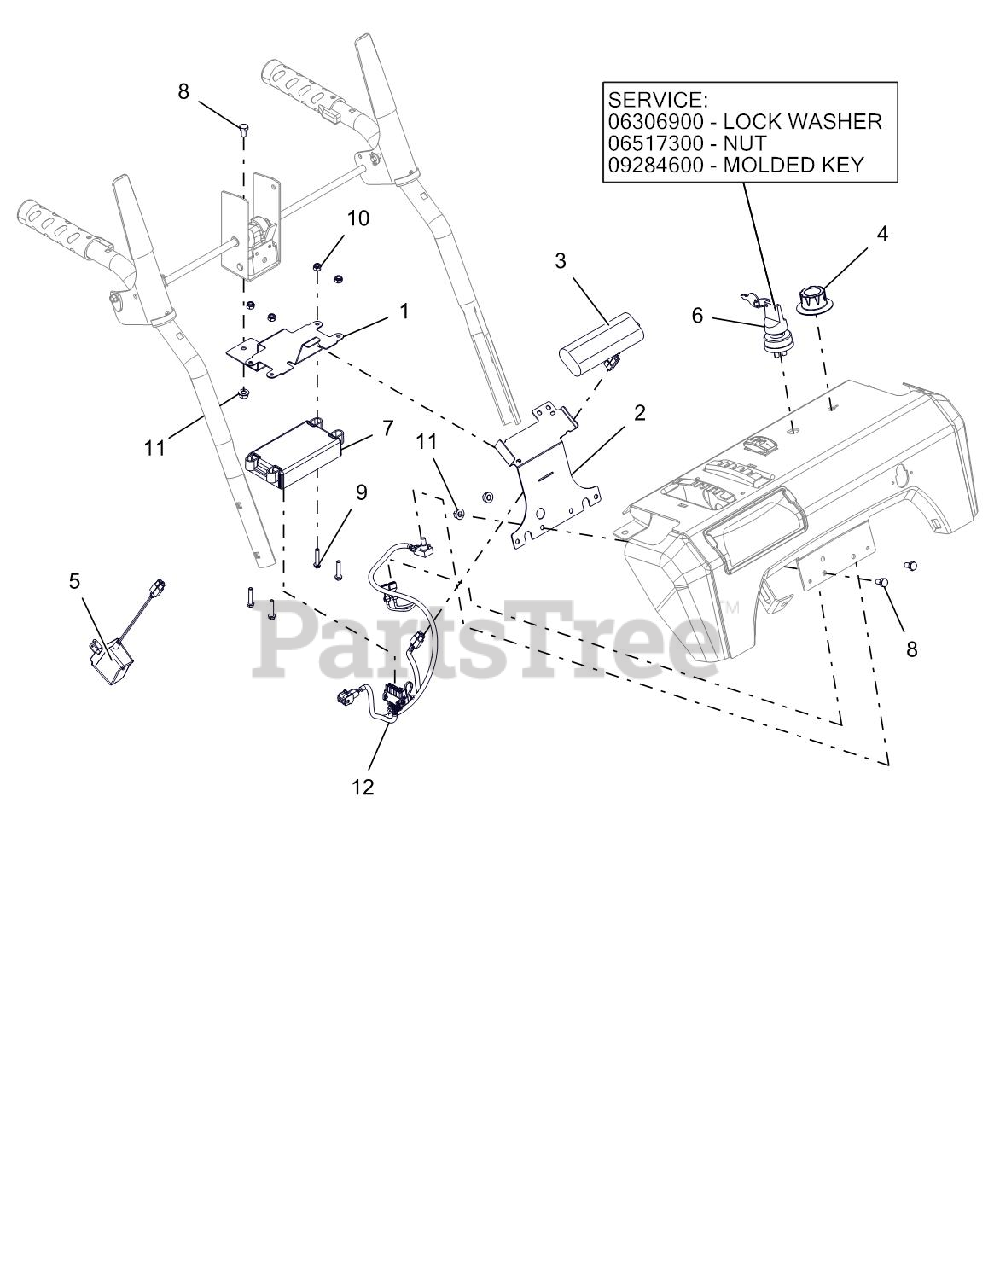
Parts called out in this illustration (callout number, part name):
1	BRACKET, ENGINE EFI-LCT LOWER
2	BRACKET, ENGINE EFI-LCT UPPER
3	BATTERY, SNOW EFI - 7.2V
4	KNOB, CONTROL - 2.063 ID
5	CHARGER, BATTERY - EFI 7.2V
6	NUT-PANEL .625-32 GRECO
6	WSHR-LK-INT .625X.045 YWZC
6	KEY W/ SHIELD
6	IGNITION SWITCH ASM - 2 POS
7	ECU SERVICE LCT/CSI - 306CC
8	@BLT-HEX .25-20X.50 GR5 YWZC
9	@SCR-MCH 10-24X1.00 HWH YWZC
10	@NUT-LK-NYL 10-24 W/INSRT YWZC
11	@NUT-LK-TOP-FLG .25-20 YWZC
12	HARNESS,WIRE - EFI ECU
